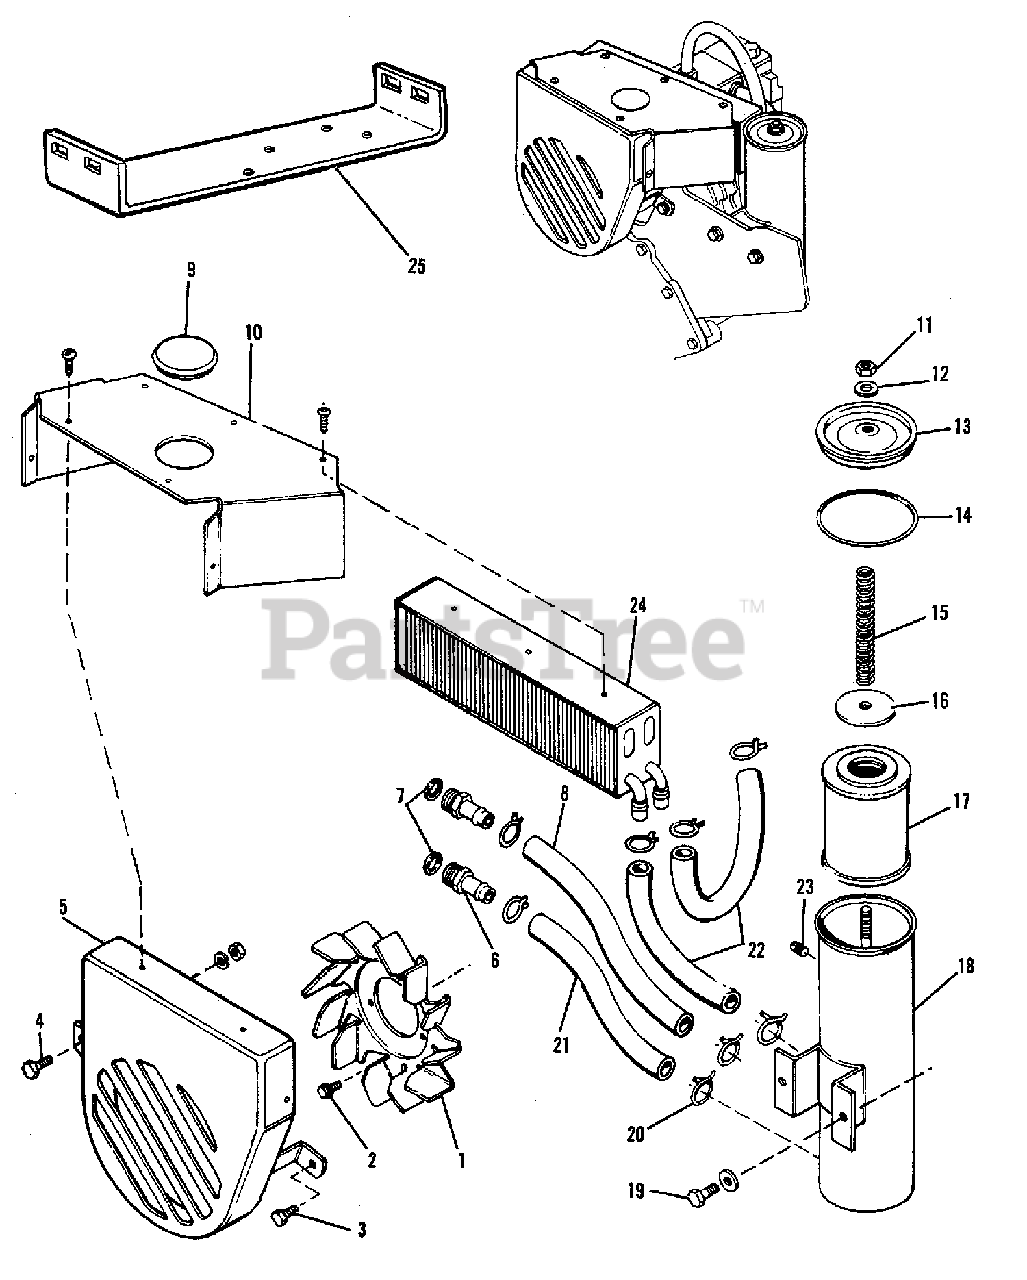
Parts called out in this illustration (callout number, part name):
1	FAN, Pulley
2	SCREW, Washer Head Tapping, 1/4NC x 1/2
3	SCREW Self Tapping, 5/16NC x 5/8
4	CAPSCREW, 7/16NC x 4
4	LOCKWASHER, 7/16
4	NUT, 7/16NC
5	SHROUD ASSEMBLY, Fan
6	INSERT, Bead
8	HOSE, Hydraulic
10	DELFECTOR, Cooler
10	SCREW, Self-Tapping, #10 x 3/8
11	NUT, Exna Lock 5/16NC
12	WASHER, Nylon
13	COVER, Reservoir
17	ELEMENT, Filter
18	RESERVOIR ASSEMBLY
19	CAPSCREW, Hexagon Head, 5/16NC x 1
19	NUT, Hexagon, 5/15NC
19	LOCKWASHER, 5/16
19	WASHER, 5/16 Standard
20	CLAMP, Hose
21	HOSE, Hydraulic
22	HOSE, Hydraulic
23	PLUG, 1/4 Square head, Plastic
24	COOLER, Oil
25	BRACKET, Cooler Support
25	SCREW, Self-Tap, #10 x 3/8
25	SCREW, #10NF x 1/2 (Round Head)
